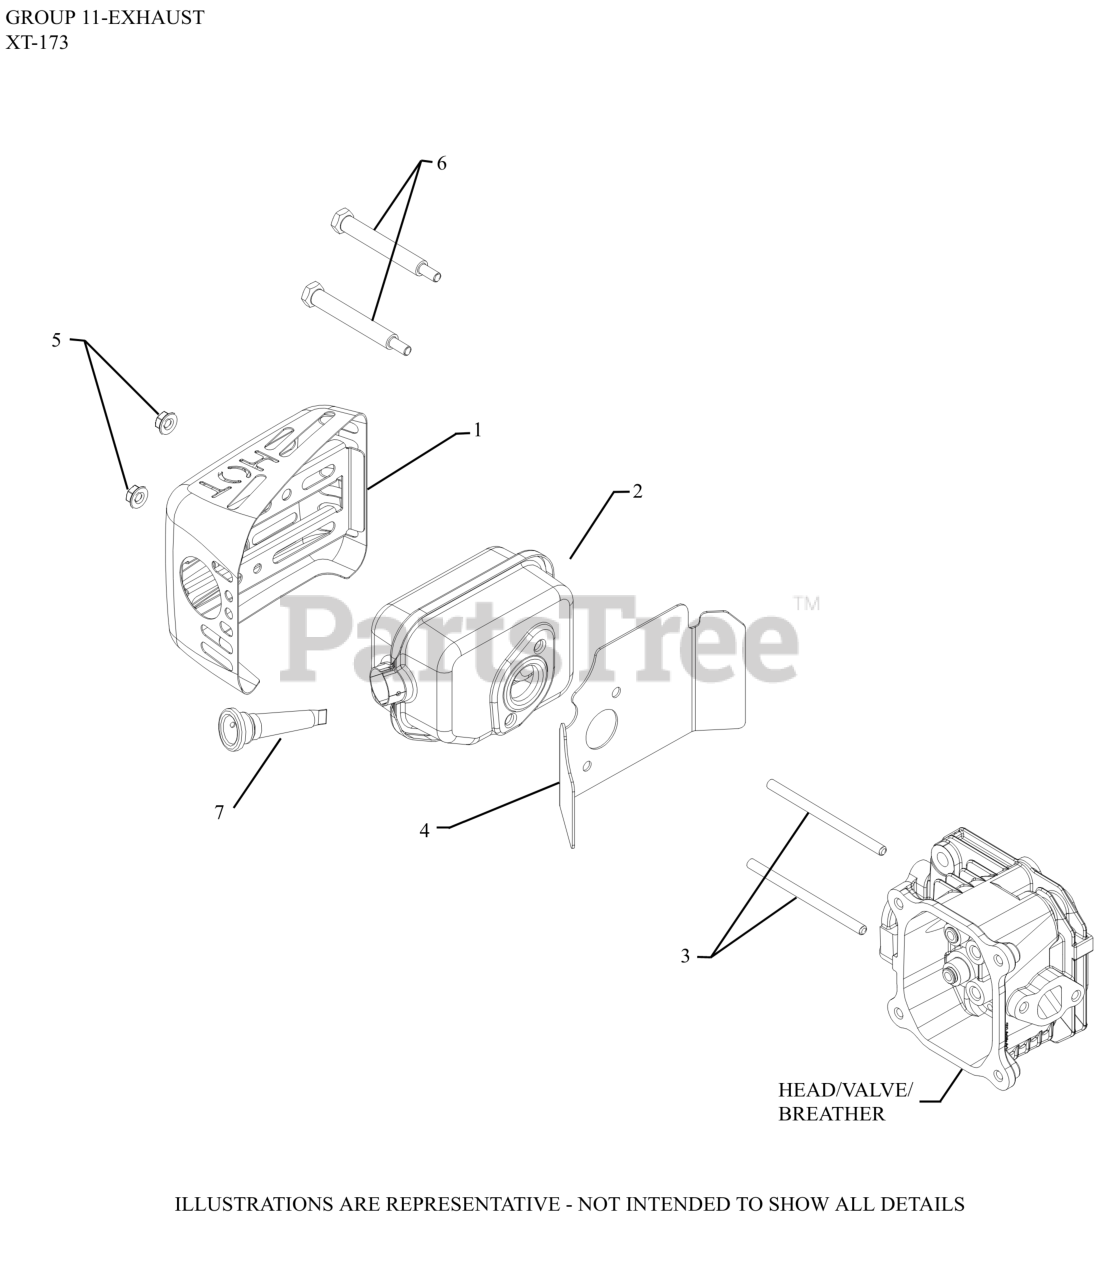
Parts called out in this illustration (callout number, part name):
1	GUARD, MUFFLER
2	KIT, MUFFLER
3	STUD (M6)
4	GASKET, MUFFLER-(#1404155S)
5	NUT, HEX FLANGE LOCK (M6)
